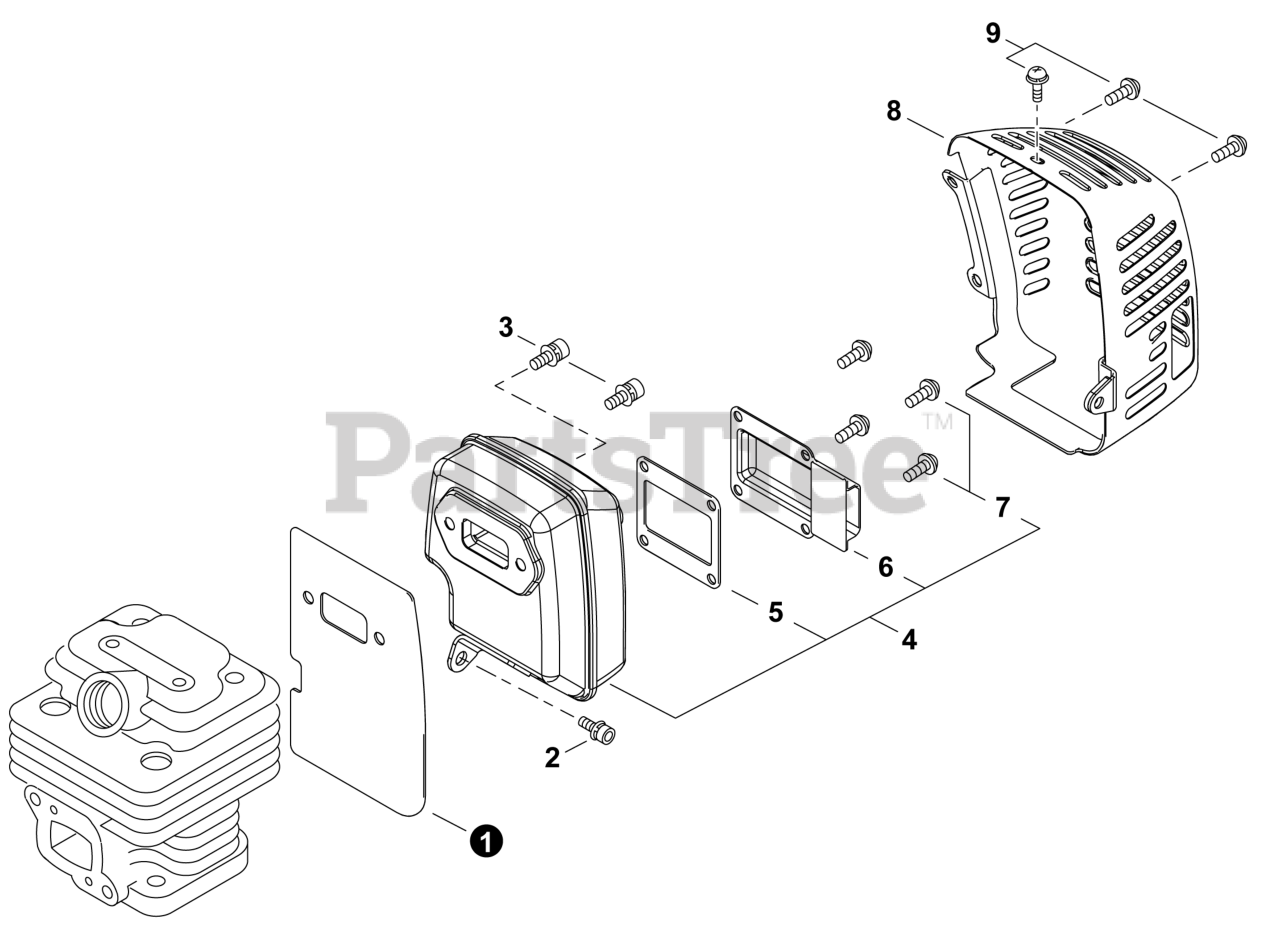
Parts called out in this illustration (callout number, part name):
1	SHIELD, HEAT
2	BOLT 5x14
3	BOLT 5x20
4	MUFFLER ASSY
5	GASKET, EXHAUST
6	GUIDE, EXHAUST
7	SCREW 4x10
8	COVER, MUFFLER
9	SCREW 4x10
